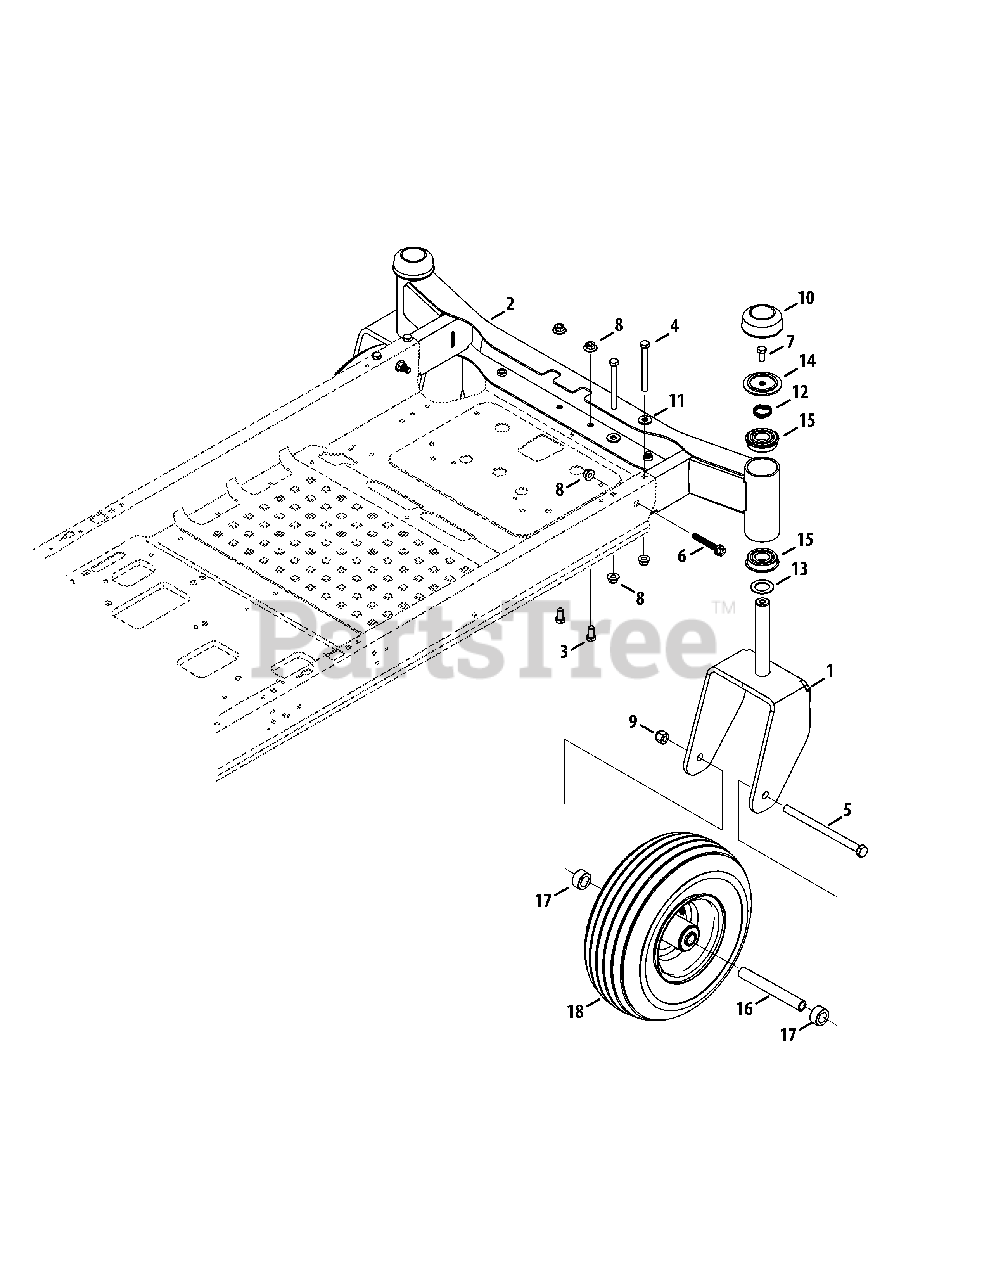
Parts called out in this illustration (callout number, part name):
1	Caster Wheel Bracket
2	Front Axle
3	Hex Cap Screw, 3/8-16 x .75
4	Hex Cap Screw, 3/8-16 x 3.75
5	Hex Cap Screw, 1/2-20 x 7.25
6	Hex Flange Screw, 3/8-16 x 2.00
7	Hex Cap Screw, 3/8-16 x .750
8	Flange Lock Nut, 3/8-16
9	Hex Lock Nut, 1/2-20
11	Flat Washer, .385 x .870 x .092
12	Wave Washer, 1.25 x 1.00 x .300
13	Flat Washer, 1.010 x 1.56 x .060
14	Shoulder Spacer, 2.50 x .200
15	Ball Bearing
16	Spacer, .51 x .75 x 5.825
17	Spacer, .76 x 1.23 x .63
18	Wheel Assembly, 13 x 5 x 6
